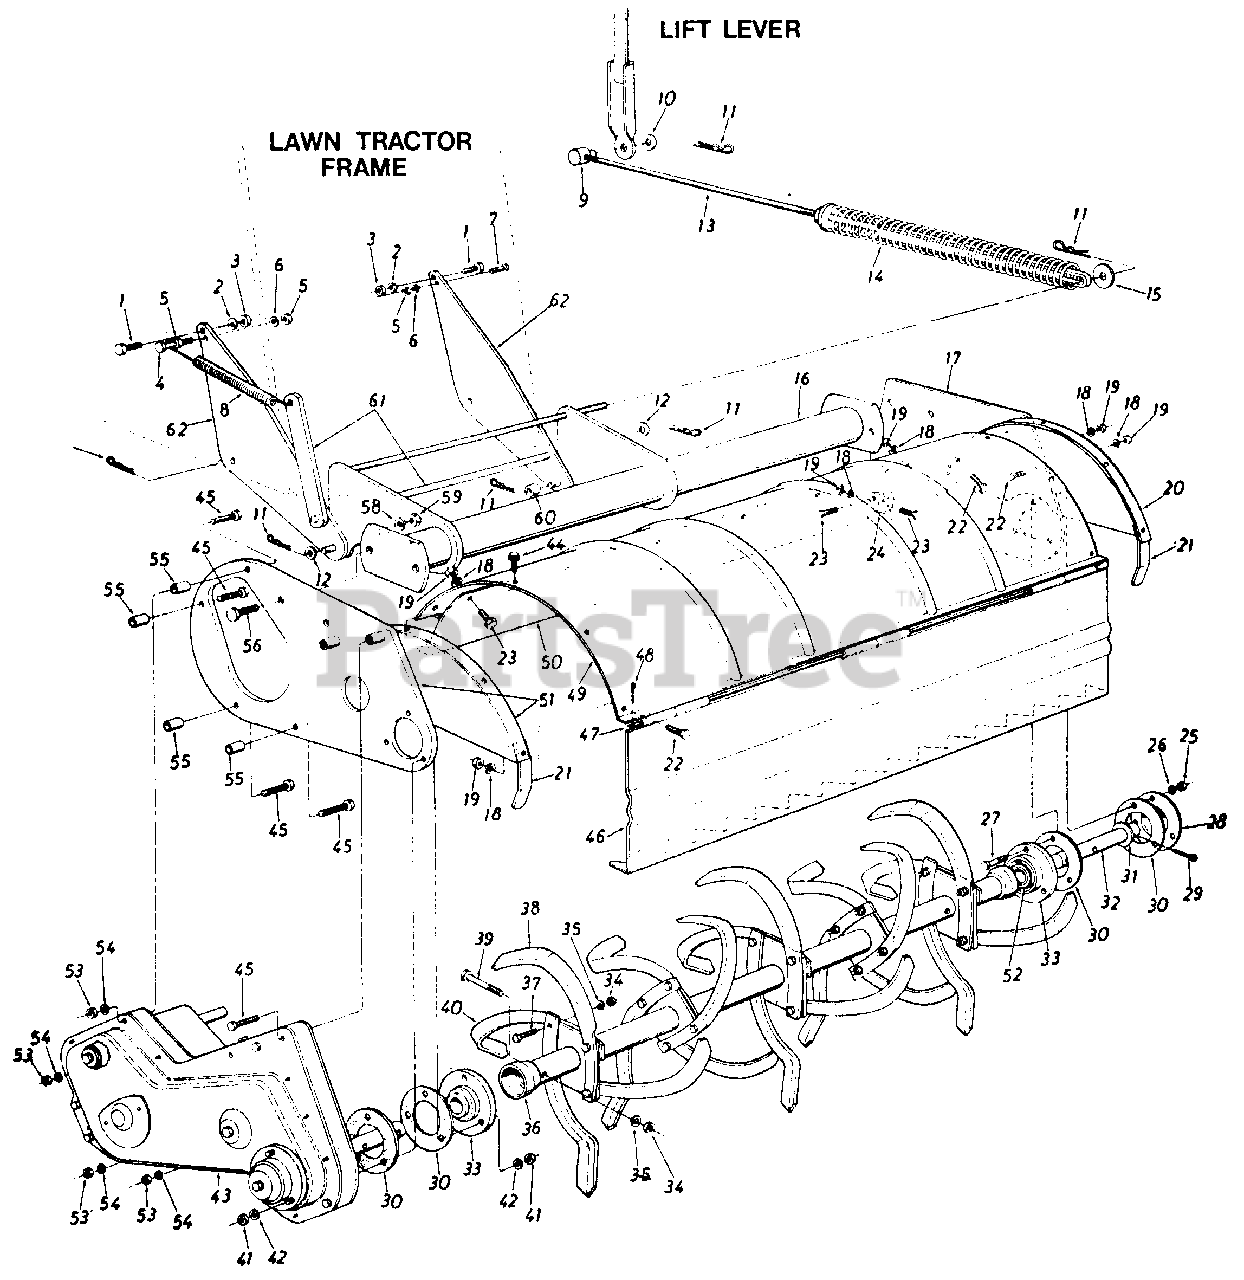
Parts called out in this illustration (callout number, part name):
1	Hex Bolt 3/8-24 x .88" Lg.*
2	L.-Wash. 3/8" I.D. Heavy Duty
3	Hex Nut 3/8-24 Thd.*
4	Hex Bolt 5/16-24 x 1.50" Lg.*
5	Hex Nut 5/16-24 Thd.*
6	L.-Wash. 5/16" I.D.*
7	Hex Bolt 5/16-24 x 1.00" Lg .
8	Extension Spring .56" O.D. x 7.75" Lg.
9	Adjustment Ferrule 1/2-13 Thd.
10	Fl.-Wash. .640" I.D. x 1.24" O.D. x .060
11	Intern. Cotter Pin 1/2" Dia.
12	Fl.-Wash. .510" I.D. x 1.0"O.D. x .060
13	Lift Rod Ass'y. 39.0" Lg.
14	Compression Spring 1.50" O.D. x 15.0" 4.
15	Fl.-Wash. .51" I.D. x 1.50" O.D. x .075
16	pivot Bracket Assembly
19	Hex Nut 5/16-24 Thd.*
23	Hex Bolt 5/16-24 x .62" Lg.*
24	Chute Pivot Bracket
25	Hex Cent. L-Nut 5/16-18 Thd.
26	L.-Wash. 5/16" I.D.*
27	Hex Bolt 5/16-18 x 1.0" 4. (Grade 5)
30	Gasket for Brg. Housing
31	Fl.-Wash. 1.25" I.D. x 2.00" O.D. x .06
32	Tine Shaft R.D. 1.25" Dia. x 6.25" 4.
33	Bearing Housing w/Bearing
34	Hex Nut 3/8-24 Thd.*
35	L.-Wash. 3/8" I.D. Heavy Duty
41	Hex Cent. L.-Nut 5/16-18 Thd.
42	L.-Wash. 5/16" I.D.*
43	Chain Case Ass'y. Comp.
44	Hex Wash. TT Tap. Scr. 5/16-18 x .62" 4.
45	Hex Bolt 1/4-20 x 2.75" Lg.*
48	Cotter Pin 1/8" Dia. x 1.00 Lg.*
53	Hex Nut 1/4-20 Thd.*
54	L.-Wash. 1/4" I.D.*
55	Spacer .28" I.D. x .62" O.D. x .90 " 4
56	Hex Bolt 1/2-13 x 1.00" 4.*
58	L.-Wash. 1/2" I.D.*
59	Hex Nut 1/2-13 Thd.*
60	Spacer. 50" I.D. x 1.00" O.D. x .50" 4.
61	Idler Bracket Support Arm Ass'y
